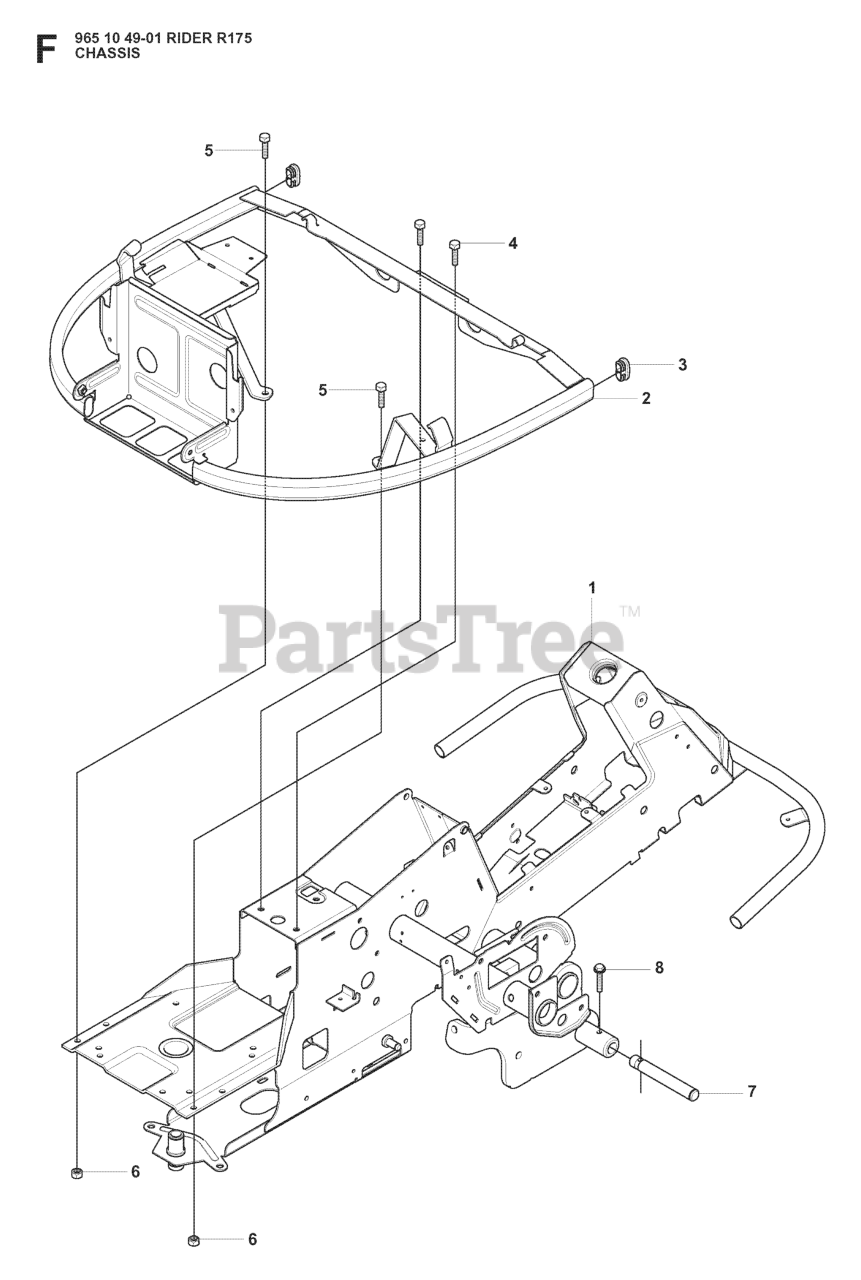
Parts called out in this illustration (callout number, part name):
2	ENGINE FRAME
6	LOCKNUT M8
8	BOLT FLANGE - M8X40\
